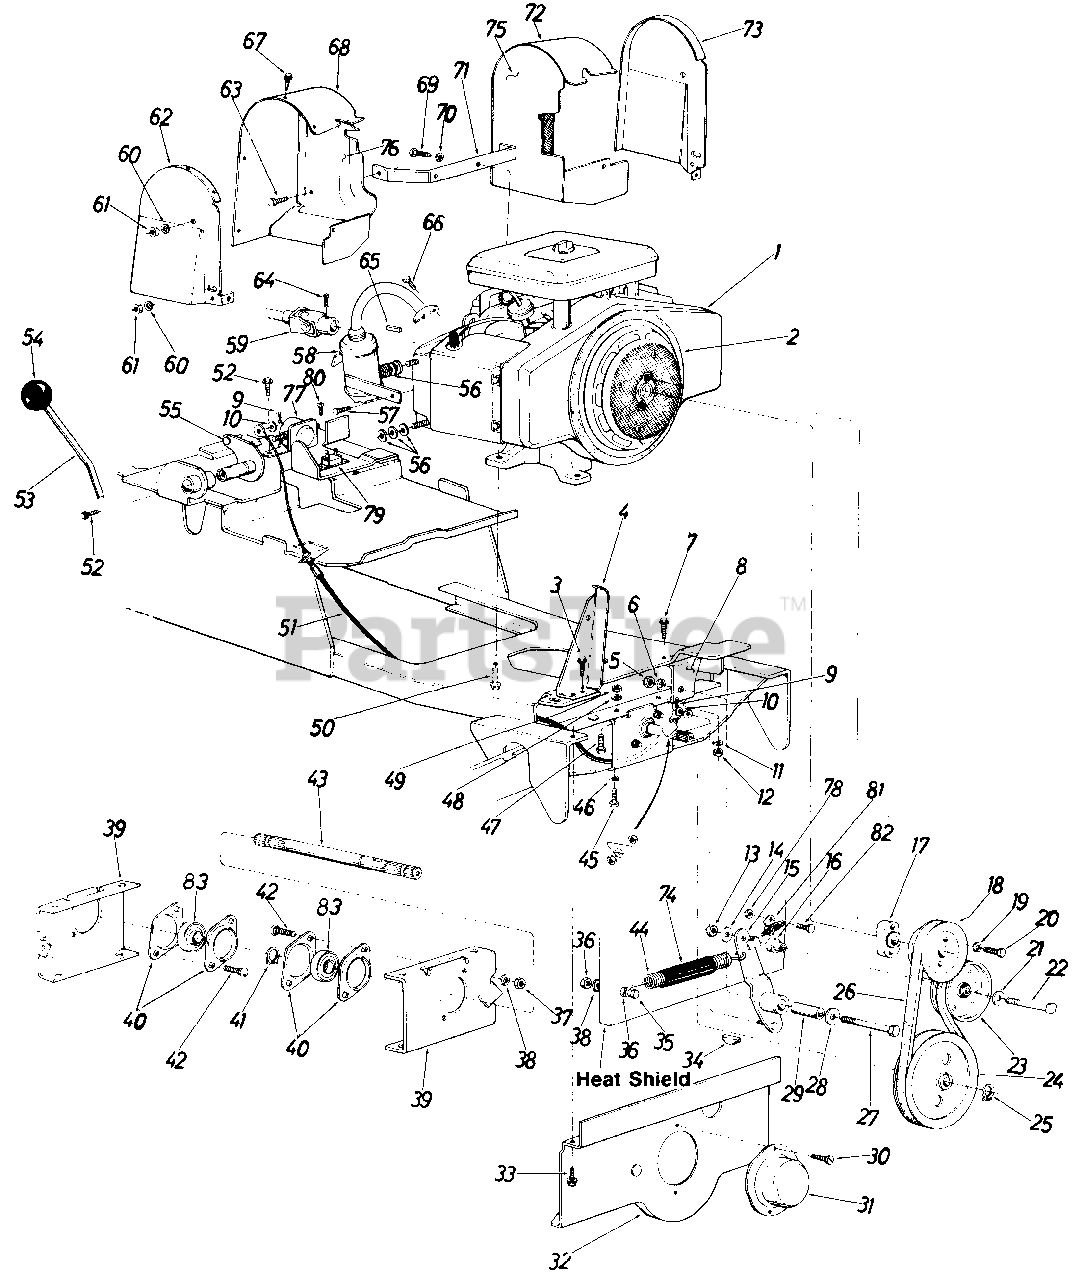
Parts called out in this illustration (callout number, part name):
1	Engine
2	Mylar Foam Strip
3	Hex Wash. Hd. Self-Tap Scr. 1/4-20 x .75" Lg.
6	L-Wash. 318" Scr.
7	Hex Wash. Hd. Self-Tap Scr. 5/16-18 x .75" Lg.
10	Fl-Wash. .38" I.D. x 1.25 0 O.D. x .10 Thk.
11	L-Wash. 3/8" Scr.
12	Hex Nut 3/8-16 Thd.
13	Hex Nut 3/8-16 Thd.
14	Fl-Wash. .38 I.D. x 1.25" O.D. x .10 Thk.
17	Pulley Spacer
18	1/2" V-Pulley 4.75" O.D.
19	L-Wash. 318" Scr. H.D.
20	Hex Scr. 3/8-16 x 2.00" Lg
21	Fl-Wash. .38" I.D. x 1.25 0 O.D. x .010 Thk.
22	Hex Scr. 3/8-16 x 2.50" Lg.*
23	Flat Idler Pulley
24	1/2" V-Pulley 7.00" O.D.
26	"V"-Belt 1/2 " X 41 " Lg.
27	Hex Scr. 3/8-16 x 2.50" Lg.
28	Fl-Wash. .38" I.D. x 1.25" O.D. x .010
29	Spacer .375" I.D. x .62" O.D. x 1.830 Lg.
30	Hex "B" Tap Scr. #10 x .50" Lg.
34	#91 Hi-Pro Key
35	Hex Scr. 5/16-18 x 1.25" Lg.
36	Hex Nut 5/16-18 Thd.
37	Hex Nut 5/16-18 Thd.
38	L-Wash. 5/16" Scr.
39	PTO Brg. Retainer Brkt.
40	1.00" Dia. Brg. w/Flangette
42	Carr. Bolt 5/16-18 x .75" Lg.
43	Spline Shaft
44	Extension Spring
45	Hex Scr. 3/8-16 x 1.00" Lg.
46	L-Wash. 3/8" Scr.
47	Hex Scr. 3/8-16 x 1.00" Lg.
48	L-Wash. 3/8" Scr.
49	Hex Nut 3/8-16 Thd.
50	Hex Wash. Hd. Self-Tap Scr. 3/8-16 x 1.25" Lg.
51	PTO Control Cable
52	Hex Wash. Hd. Self-Tap Scr. 1/4-20 x .50"
54	Ball Knob
55	PTO Actuator Lever Ass'y.
56	Fl-Wash. .312" I.D. x 1.620" O.D. x .060
57	Hex Wash. Hd. Self-Tap Scr. 1/4-20 x .50" Lg.
58	Muffler Ass'y. Comp. R.H .
59	Universal Joint Ass'y. Comp.
60	Fl-Wash. .312" I.D. x 630n O.D. x .063
61	Hex Nut 5/16-18 Thd.
62	Shroud Outer R.H.
63	Hex Wash. Hd. Self-Tap Scr. 1/4-20 x .50" Lg.
64	Sq. Hd. Set Scr. 5/16-18 x .38" Lg.
65	Sq. Key 1/4" x 2.00" Lg.
66	Hex Wash. Hd. Scr. 1/4-20 x 518" Lg. Grade 5
67	Hex "AB" Tap Scr. #10 x .50" Lg.
68	Shroud Cover R.H.
69	Hex Scr. 5/16-24 x .75" Lg.
70	L-Wash. 5116" Scr.
71	Shroud Support Brkt.
72	Shroud Cover L.H.
73	Shroud Outer L.H.
74	Spring Cover Tubing
75	Shroud Inner Ass'y. L.H.
76	Shroud Inner Ass'y. R.H.
77	Solenoid
78	Hex Scr. 1/4-20 x 1/2" Lg.
79	Circuit Breaker
80	Truss Mach. Scr. #10 x .50" Lg.
81	Safety Switch
82	L-Wash. 1/4" Scr.
83	Ball Bearing
